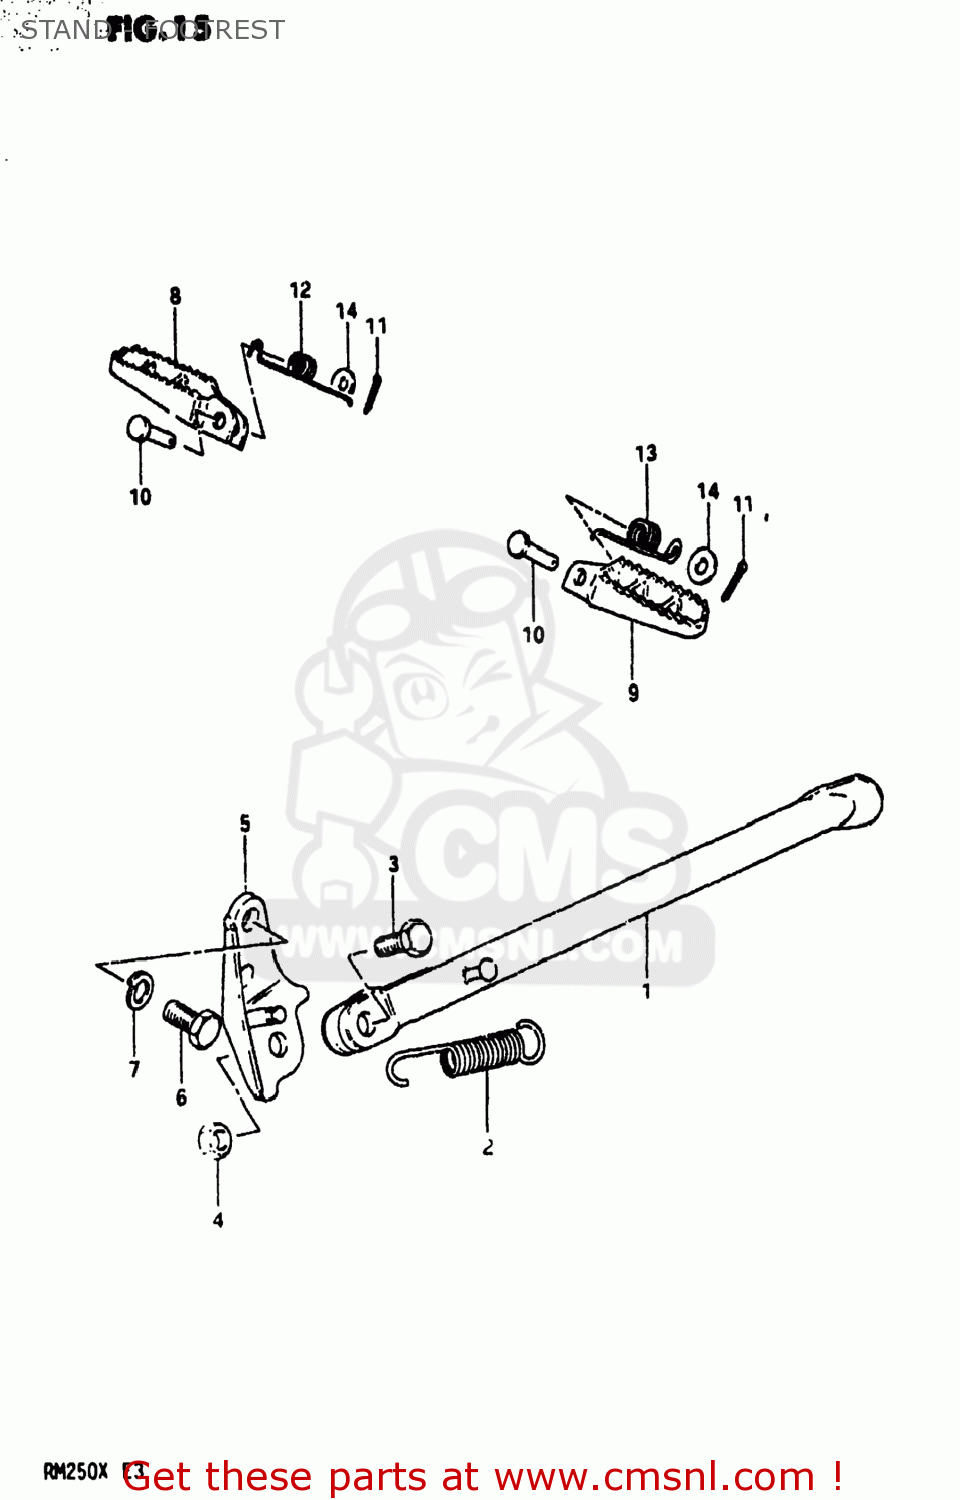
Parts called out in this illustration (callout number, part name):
1	STAND,SIDE
2	SPRING
3	BOLT(10X30)
4	NUT
5	BRACKET,SIDE STAND
6	BOLT(10X19)
7	LOCK WASHER
8	FOOTREST,RIGHT
9	FOOTREST
10	PIN
11	PIN 20X20
12	SPRING
13	SPRING
14	WASHER
